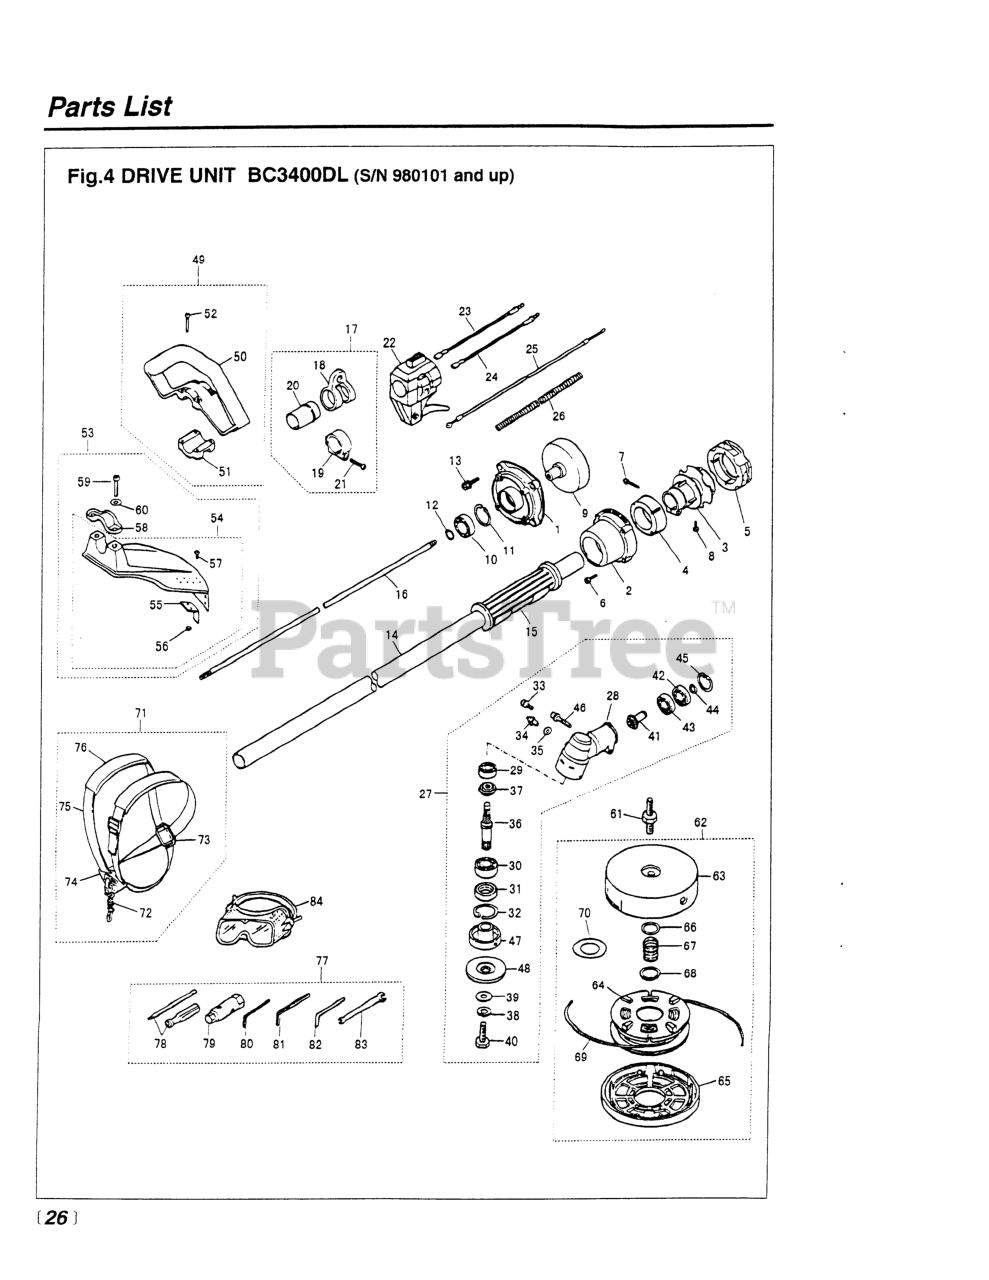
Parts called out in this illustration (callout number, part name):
1	HOUSING
2	CAP
3	JOINT
4	ABSORBER-F
5	ABSORBER-R
6	BOLT, M5 X 30
7	BOLT, M6 x 30
8	BOLT, M5 X 10
10	BEARING
11	RING, SNAP, M35 X 1.5
12	RING, SNAP, M15 X 1.0
13	BOLT, M6 x 20
14	PIPE COMP.
16	SHAFT, DRIVE (USE -12211)
17	HANGER ASSEMBLY
18	HANGER
19	CLAMP
21	SCREW, M5 x 25
23	CORD (A), BLACK
24	CORD (B), RED
25	CABLE COMP (RPLS 1633-83100)
26	TUBE
28	GEARCASE (RPLS -13113)
29	BEARING (RPLS T3403-13510)
31	SEAL, OIL
32	RING, SNAP, M32 x 1.2
33	BOLT, M5 X 10
34	FITTING, GREASE
35	WASHER, M6 X .8
36	SHAFT
37	GEAR, BEVEL
38	WASHER (RPLS 3180-13270)
39	WASHER, M8 x 2.3 (RPLS -20823)
40	BOLT, LH
41	PINION
43	BEARING (RPLS T3403-13510)
44	RING, SNAP
45	RING, SNAP, M26 X 1.2
46	BOLT, M6 x 1.35
47	HOLDER (A)
48	HOLDER (B)
49	HANDLE ASSEMBLY
50	HANDLE
51	CLAMP
52	SCREW, M5 x 35
53	GUARD ASSY (RPLS -24001)
54	GUARD COMP
55	BLADE
56	NUT
57	SCREW, M5 x 12
58	CLAMP
59	BOLT, M6 x 1.30
60	WASHER, M6 X 15
61	SHAFT (RPLS 3274-99120)
62	6
63	CASE (USE -99112)
65	COVER
66	PLATE, LARGE
68	PLATE, SMALL
69	CORD
70	SPACER
74	HANGER COMP.
75	BAND (NOT SOLD SEPARATELY)
76	PROTECTOR
77	TOOL SET
78	SCREWDRIVER
80	WRENCH (TOOL)
81	WRENCH (TOOL)
82	BAR
83	SPANNER, 8 X 10 (RPLS 2540- )
